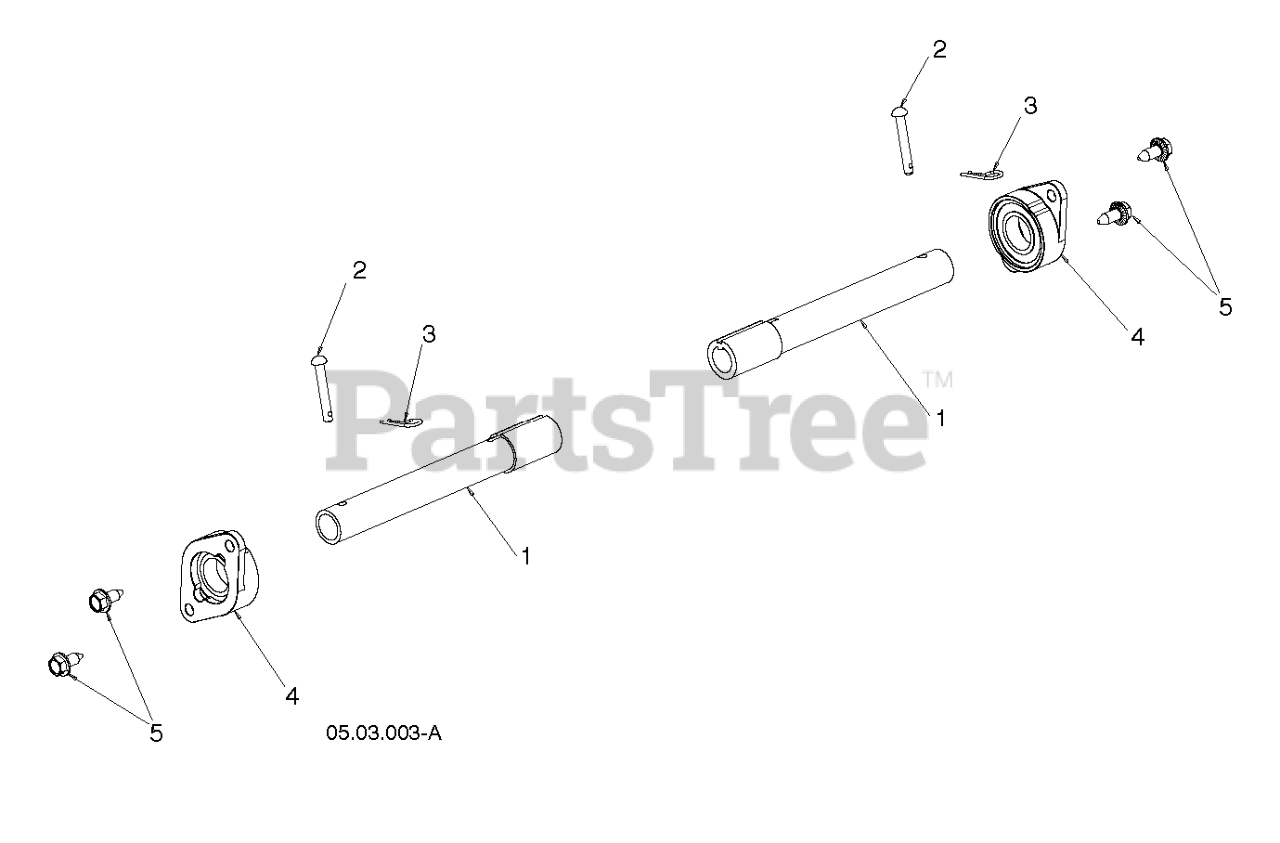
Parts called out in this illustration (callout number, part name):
1	AXLE WHEEL
2	RIVET,DRILLED
3	RETAINER M
4	CARRIER BEARING
5	BOLT.HEX.HD.WASHER.5/16-18X.75
